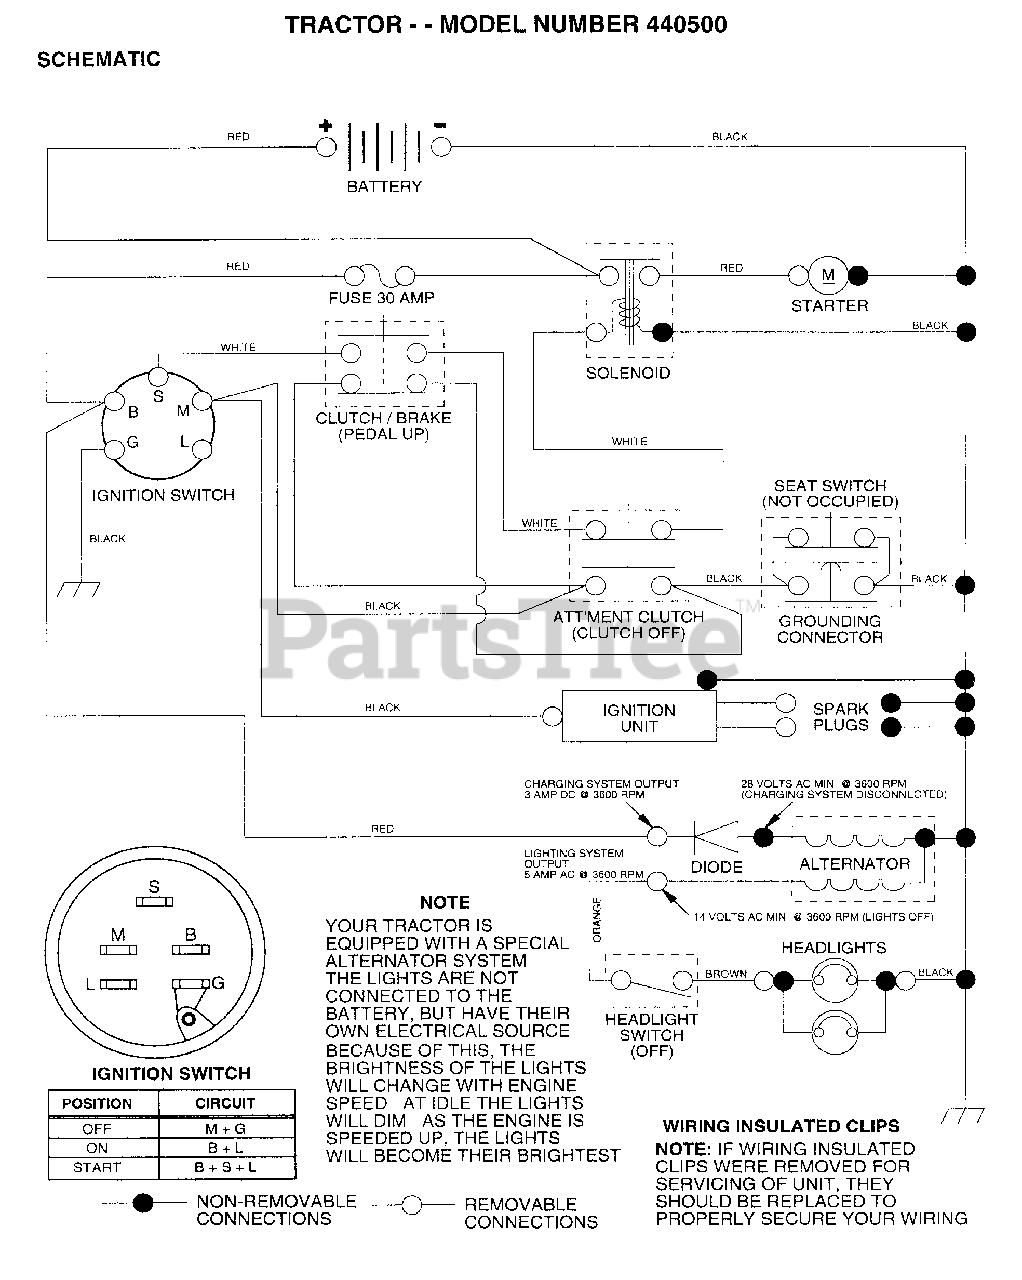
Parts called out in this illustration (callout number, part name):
2	BOLT LT
3	WASHER
4	LOCKWASHER
7	TUBE T
9	HOSE CLAMP T
15	FASTNER.SNAP-IN
20	NUT
21	"HARNESS,LIGHT SOC"
22	HEADLAMP BULB
24	CABLE-BATTERY T
25	CABLE.BTRY.6GA.RD
26	FUSE HYT
28	CABLE T
29	SWITCH SEAT
30	SWITCH IGN 4POS
31	NUT IGNITION
32	COVER KEY SWITCH
33	KEY
35	BRACKET LT
36	SCREW
38	BRACKET SWITCH IN
39	SWITCH INTERLOCKT
40	HARNESS.IGNITION
41	BOLT HXHD FIN
44	NUT HXKEP 1/4X20
48	ADAPTER AMMETER
52	PROTECTION LOOP
70	HARNESS.ENG.LT.
